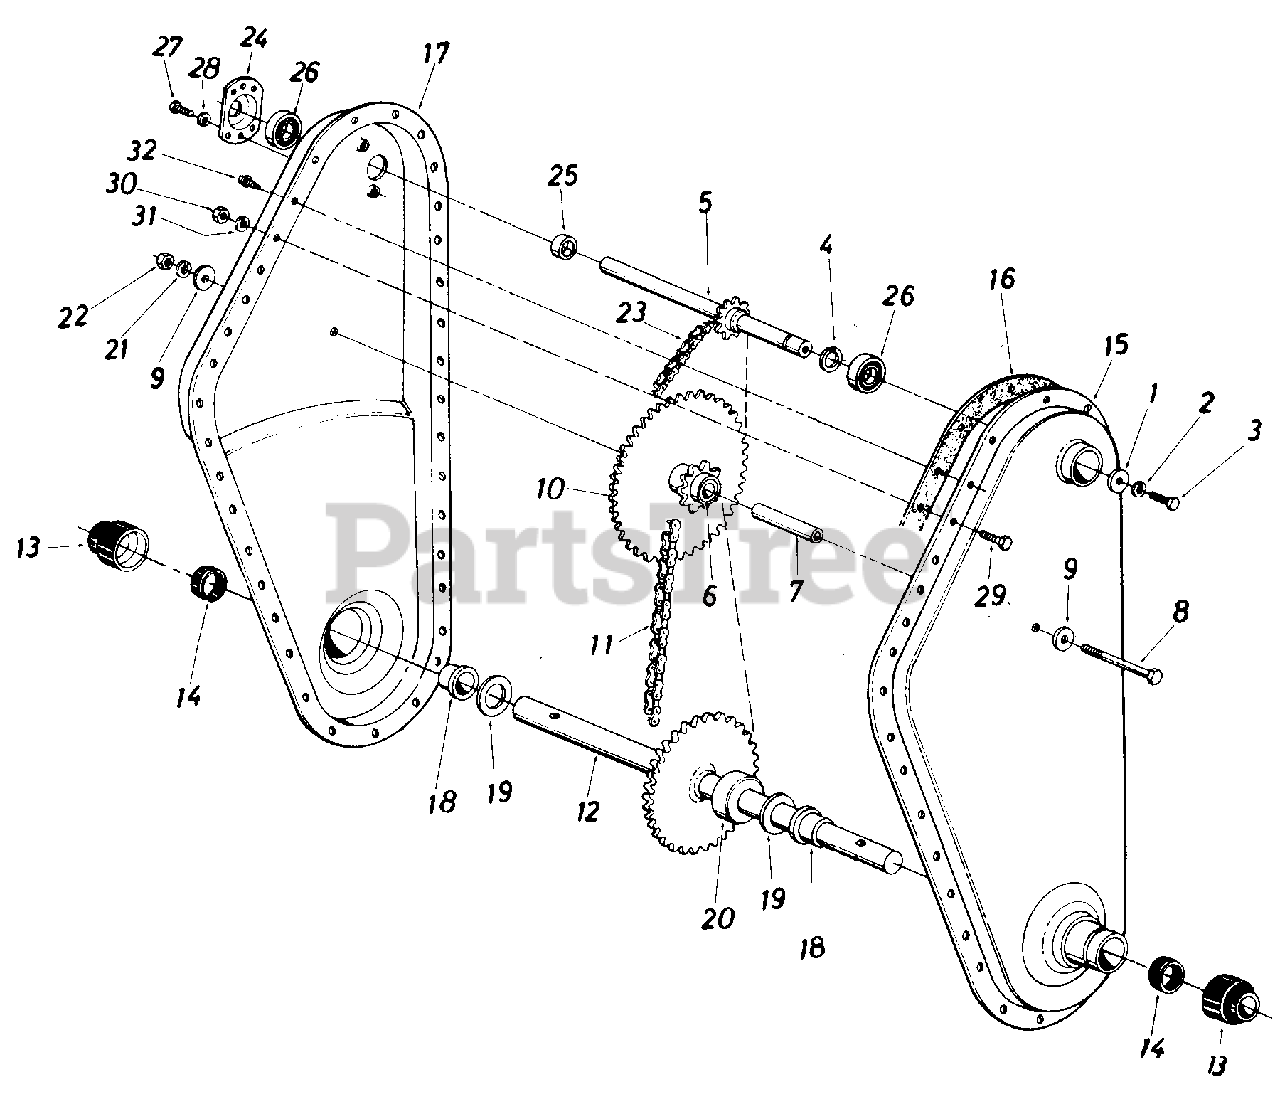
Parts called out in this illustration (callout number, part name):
1	Fl-Wash. 1/4" I.D. x .93" O.D. x .1 20
2	L-Wash. 1/4" I.D.
3	Hex Bolt 1/4-28 x .62" Lg. w/ Patch
4	External Snap Ring-518" Dia.
5	Input Shaft Ass'y.
6	Bearing 5/8" I.D. x 3/4" O.D. x 1.860" Lg.
7	Sprocket Hub Tubing 3/8" I.D. x 5/8" O.D. x 1.90
8	Hex Bolt 3/8-24 x 2.75" Lg.
9	Fl-Wash. 3/8" I.D. x 1.25" O.D. x .10
10	Sprocket Ass'y.
11	#50 Chain 5/8" Pitch x 46 Links Endless
12	Tine Shaft Ass'y.
13	Dust Cup
14	Seal Ring Single Lip, Springless
19	Fl-Thrust Wash. 1.0" I.D. x .03 Thk.
20	Step Spacer
21	L-Wash. 3/8" I.D.
22	Hex Nut 3/8-24 Thd.
23	#35 Chain 3/8" Pitch x 52 Links Endless
24	Bearing Housing 1.38" I.D.
25	Spacer
26	Ball Bearing .625" I.D. x 1.38" O.D. x .437
27	Hex Wash. SF-Tap Scr. 1/4-20 x.50" Lg.
28	L-Wash. 1/4" I.D.
29	Hex Bolt 5/16-18 x .75" Lg.
30	Hex Nut 5/16-18 Thd.
31	L-Wash. 5/16" I.D.
32	Hex Wash. SF-Tap Scr. 1/4-20 x.50" Lg.
